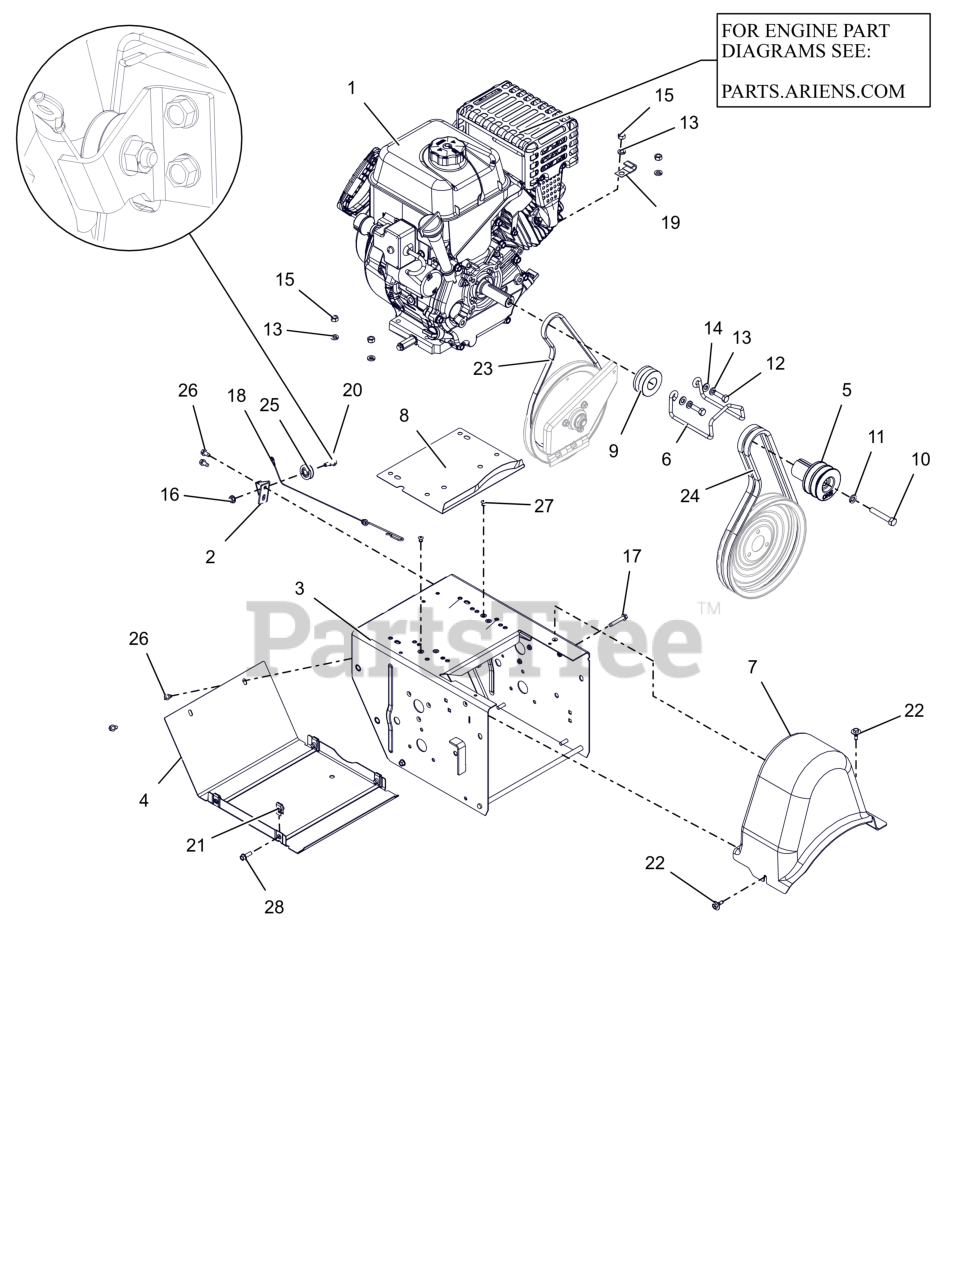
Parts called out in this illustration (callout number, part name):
1	ENGINE, ARIENS AX291 240V/60W
2	BRACKET, CABLE PULLEY
3	FRAME, MAIN - 14GA DELUXE (ORANGE)
4	COVER, BOTTOM
5	SHEAVE,ATTACHMENT-SHO 2 GRV
6	FINGER, BELT
7	COVER, BELT-LARGE
8	BAFFLE, WATER - LARGE BLOCK
9	SHEAVE, TRACTION (KEYLESS)
10	BLT, HEX .38-24X2.25 G5 ZCC
11	WSHR,LK-REG .375X.094 ZCC
12	BLT, HEX 0.3125-24X1 G5 ZCC
13	WSHR, LK-HVY .312X.097 ZCC
14	WSHR,FLT .344X.688X.065 ZCC
15	NUT, HEX .312-18 ZCC
16	NUT-LK-TOP-FLG .250-20 GF ZCC
17	SCR,TAP .25-20X1.50 HWH TR ZCC
18	CABLE, LOWER TRACTION,SS & PRO
19	J-CLAMP
20	BOLT, SHLDR -.375 X .375 X .25-20
21	NUT-RTNR .25-20X.56
22	SCR-TAP .25-20X.5 CAPTIVE
23	V-BELT, 3L-WRAPPED
24	V-BELT, HA-RAW EDGE (SET)
25	PULLEY, CABLE
26	SCR-TAP .25-20X.50 HWH ZCC
27	RVT, POP .1875 ZCC
28	BLT, HWH .25-20X.75 G5 ZCC
